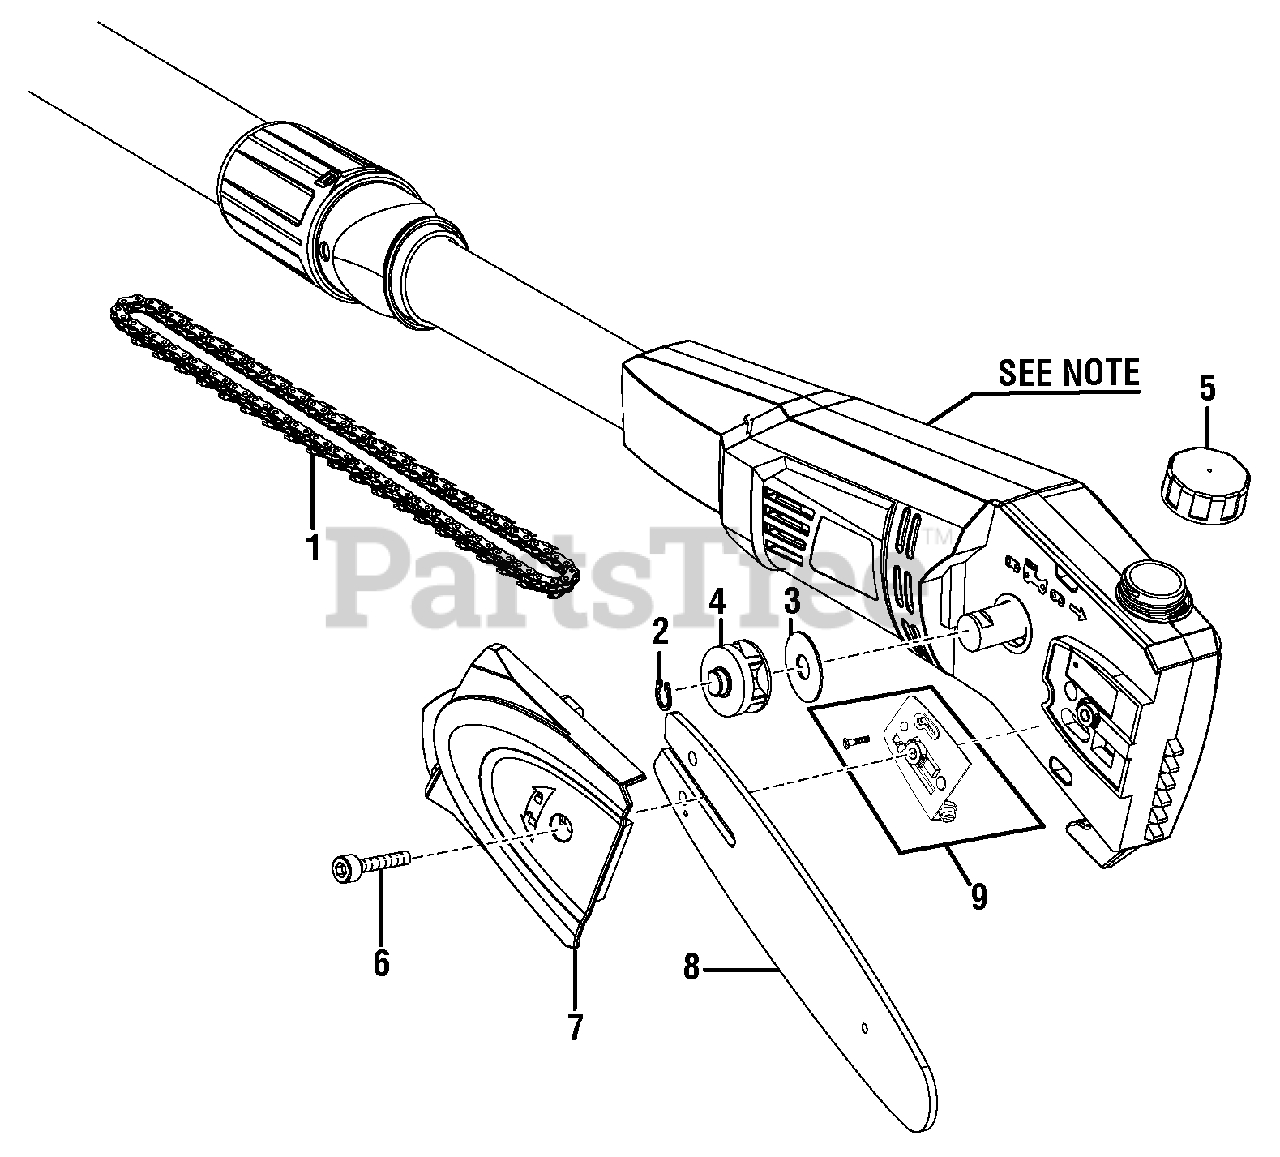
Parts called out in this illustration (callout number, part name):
2	Retaining Ring
6	Screw (M5 x 45 mm, Soc. Hd.)
7	Chain Cover Assembly
8	Bar w/Label
9	Chain Adjustment Assembly
